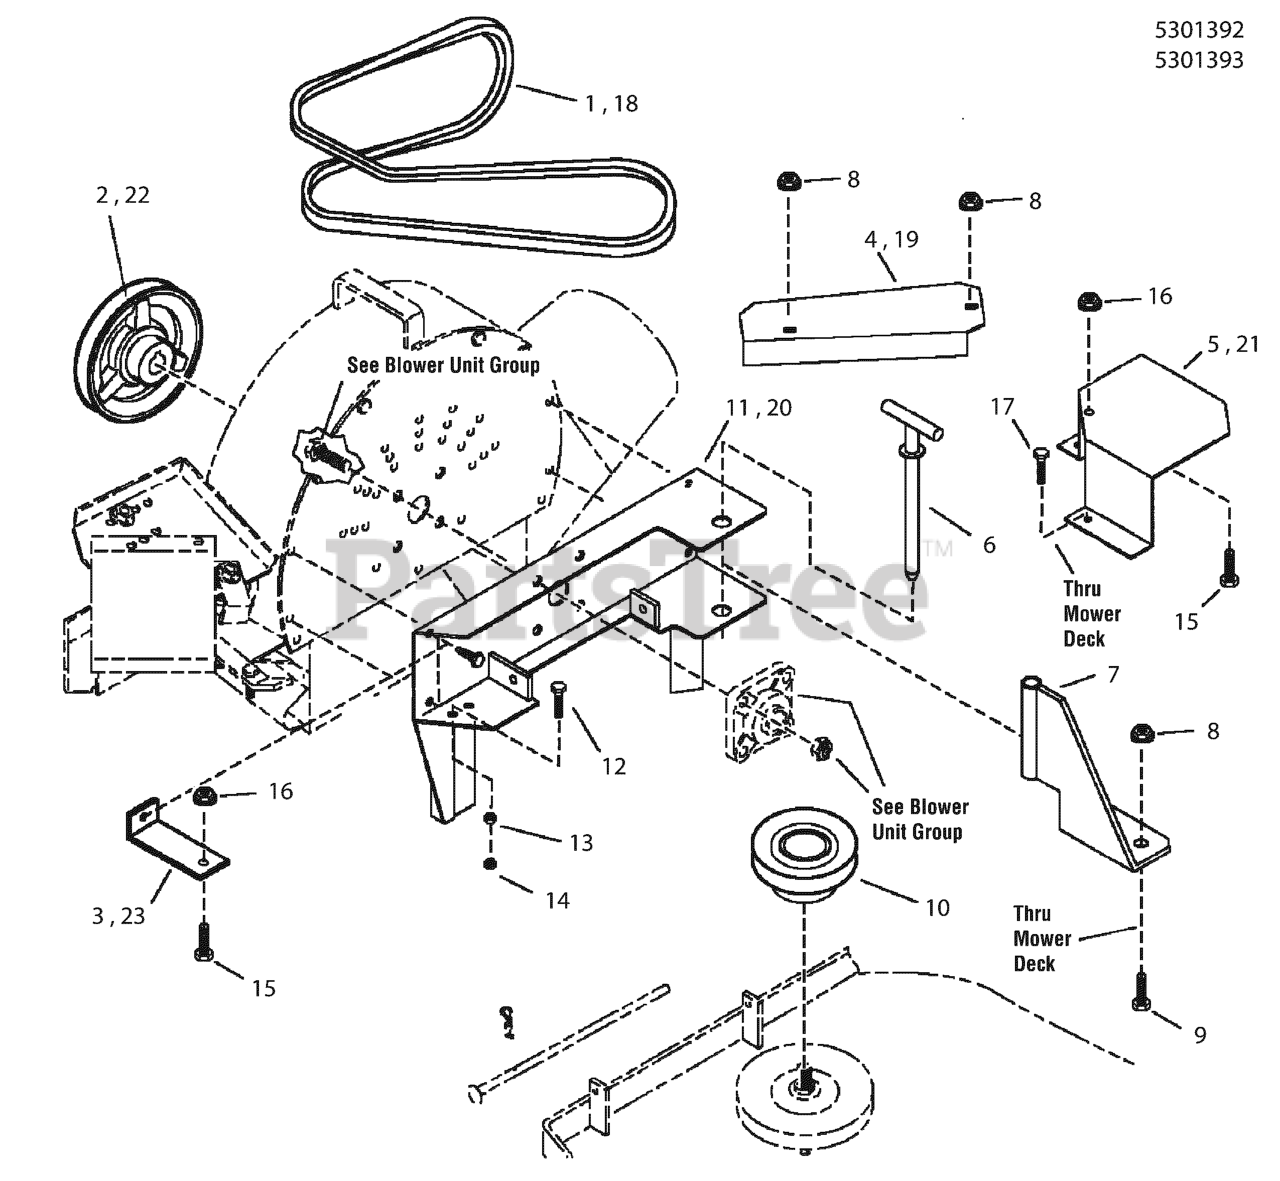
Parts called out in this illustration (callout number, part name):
1	BELT, Blower Unit Drive, A92
2	PULLEY, BLOWER INPUT
3	BRKT, GUARD SUPPORT - BLK
4	GUARD, BELT, MODEL 52 - BLK
5	COVER, BELT, DECK - BLK
6	WELD, PIN, T-HANDLE LOCKING, ZP
7	WELD, DECK MOUNT BRKT. - BLK
8	NUT, 3/8-16 HEX NYLOCK FLANGE
9	BOLT, 3/8-16 X 1" GD5 CZ
10	PULLEY, SPINDLE, FAST VAC
11	WELD, BLOWER MOUNT, 52 - BLK
12	BOLT, 5/16-18 X 1-1/4 GD5 YZ
13	NUT, 5/16-18 HEX NYLOCK FLANGE
14	NUT, 5/16-18 HEX TOP LOCK
15	BOLT, 3/8-16 X 1-1/4" GD5 CZ
16	NUT, 3/8-16 HEX SERRATED FLANGE
17	BOLT, 5/16-18 X 3/4, SELF-TAPPING
18	BELT, A-SEC, 92.00EL, ARAMID, WRPD
19	GUARD, BELT, 61 NZM - BLK
20	WELD, MOUNTING BRACKET, 61" NZM - BLK
21	GUARD, PULLEY, 61 NZM - BLK
22	PULLEY, BLOWER, 61" SNAPPER
23	BRKT, MOUNTING, LOWER GUARD - BLK
